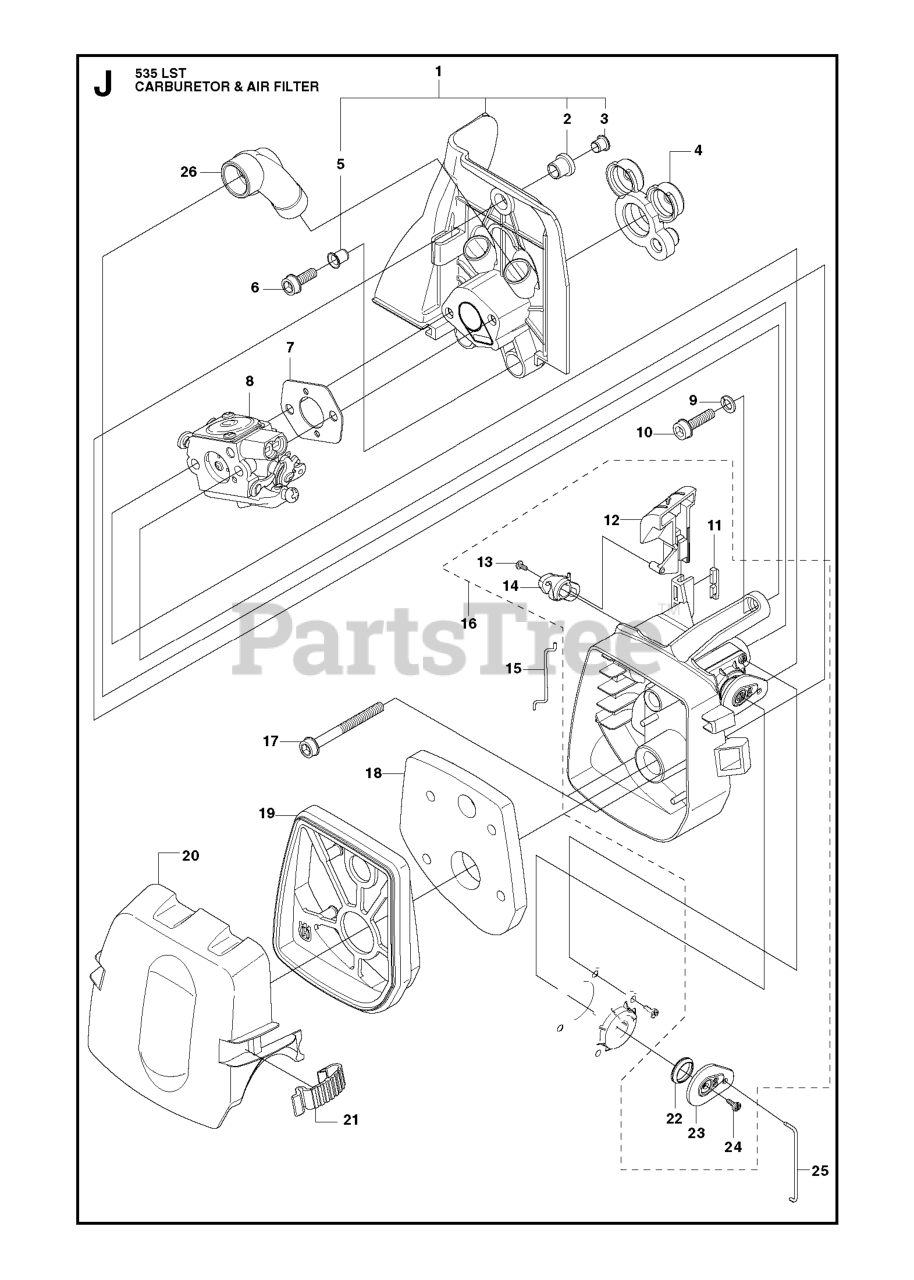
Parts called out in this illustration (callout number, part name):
1	DECAL
2	DECAL.ENG.25HP.KAWA.HSQV.XP
3	RH HOOD DECAL
4	LH HOOD DECAL
5	DECAL HOOD SIDES
6	DECAL.INTERNATIONL.CUTFINGER
8	DECAL, DASH
8	CARBURETTOR
9	DECAL, FENDER
10	DECAL READ OWNER'S MAN SYMS
11	DECAL, FOOTREST
12	CHOKE CONTROL
13	DECAL V-BELT SCHEMATIC
14	DECAL CLUTCH/BRAKE
15	DECAL.WHEEL.STEERING.HUSQ.PERM
15	THROTTLE ROD
16	FILTER HOLDER
17	DECAL PARK BRAKE
18	AIR FILTER
20	COVER, AIR FILTER
23	REFLECTOR-TAIL YT
24	DECAL BTRY SYMBOLS
25	THROTTLE ROD
27	DECAL.BYPASS.FENDER.CRD.LT.YT
